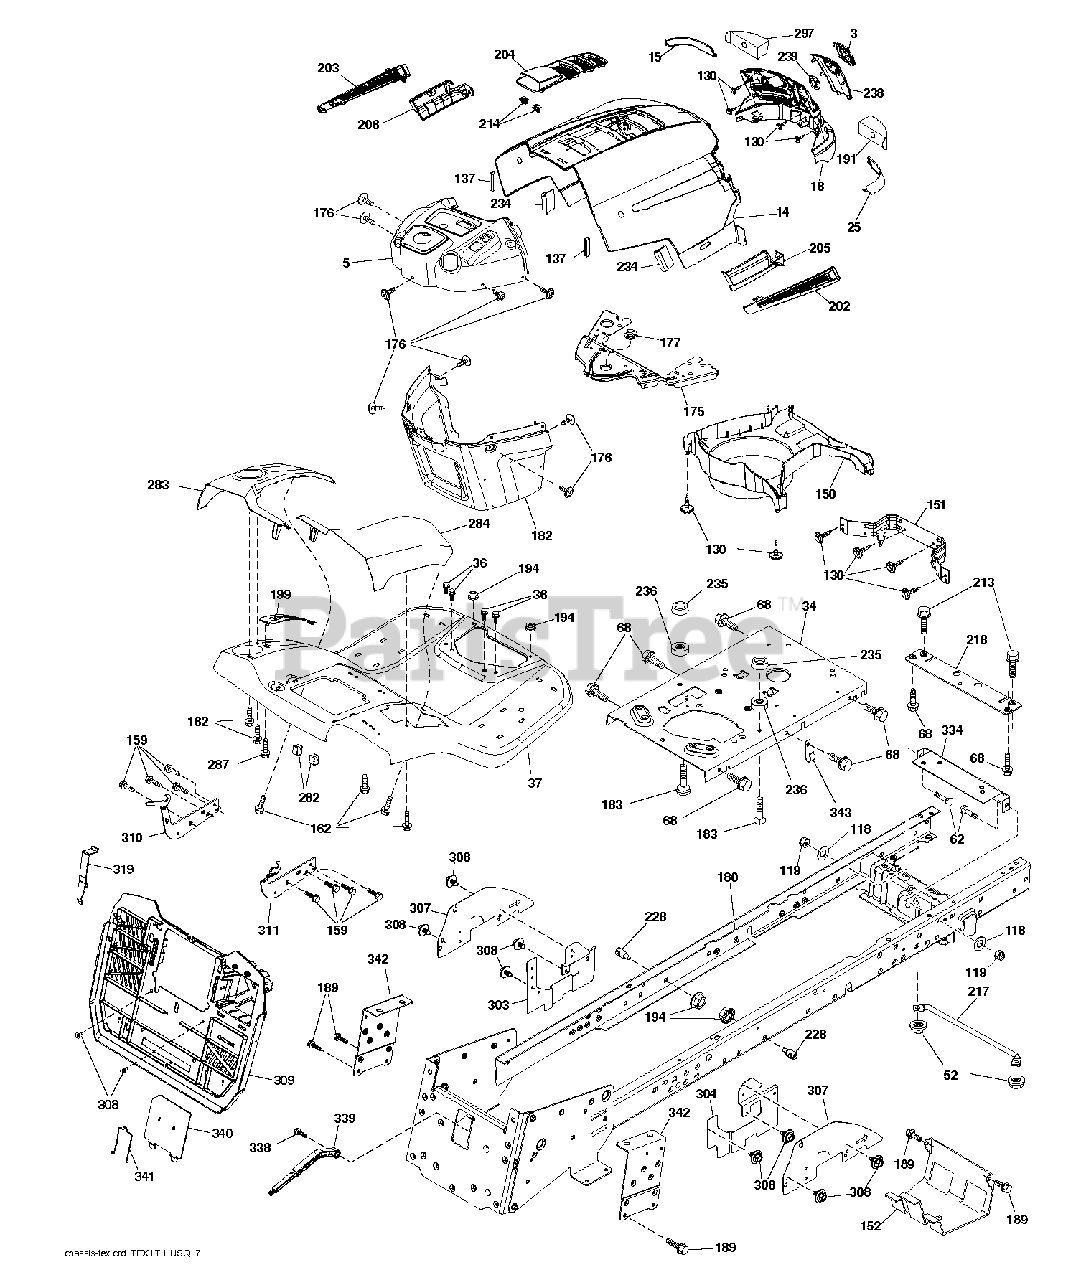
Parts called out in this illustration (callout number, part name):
3	LOGO.HUSQ.GT.LT.CROWN.H
5	DASH.HUSLT.PTO.RS.CHG.SRV.498
14	HOOD.HUSQVARNA.LT.ORANGE
15	LENS.HUSQVARNA LT.RH
18	GRILLE.SVC.HUSQVARNA.GREY
25	LENS.HUSQVARNA LT.RH
34	PLATE.ENGINE.10GA.CRD.GENII
36	SCREW 5/16"
37	FENDER.TEX.SRD.CRD.FRN.GUARDS
52	LOCKNUT
62	BOLT D
68	SCREW LT
118	WASHER
130	SCREW.#10 X 0.750.BOS
137	BUMPER DASH
151	BRACKET PIVOT
152	SHIELD.BROWNING.W/TEX
159	SCREW, 3/8-16X3/4
162	SCREW.HI-LO.CONSOLE
175	CROSSMEMBER
176	SCREW.#10-24X5/8.RN.QU
177	BUSHING STEERING
180	CHASSIS WLDT TEX CRD
182	DASH.LOWER.PREDATOR LT
183	BOLT.5/16-18X1-1/4 FULL THD
189	SCREW
191	INSERT.REFLECTIVE.RH.
194	NUT LOCK HEX FLANGE 5/16-18
199	PLATE DECK LIFT
202	VENT.SIDE.HUSQVARNA.LT.RT
203	VENT.SIDE.HUSQVARNA.LT.LFT
204	SUBASM.TOP.VENT.HUSQ.LT
205	SKIRT.SIDE.HUSQVARNA.LT.RT
206	SKIRT.SIDE.HUSQVARNA.LT.LEFT
213	BOLT
214	CLIP.RETAINER.TINNER.
217	ROD.PIVOT.HOOD
218	X-PIECE.HOOD.STOP.NON/
228	STUD.FASTNER.W/ANTI-ROTATE
234	BUMPER.HOOD.TEX.HUSQVARNA
235	SPACER FENDER
236	NUT.CENTERLOCK.5/16-
238	TRIM.HUSQ LT.668
282	CLIP.RETAINER.CONSOLE.LT.HUSQ
283	CONSL.DECKLIFT.LH.SRD.TEX.CRD
284	CONSL.SHFT.PEDAL.RH.SRD.TEXCRD
287	SCREW 1/4X20
297	INSERT REFLECTIVE
303	SHIELD.LWR.LH.LT.30"CRDSRD.PNT
304	SHIELD.LOWER.RH.CRD.GEN.PNT
307	SHIELD.UPPER.CRD.SRD.ISO
308	BOLT, 5/16-18 X 1 3/4
309	BACKPLATE.TEX.CRD
310	BRACKET BRACKET.LH FRONT BAG H
311	BRACKET BRACKET.RH FRONT BAG H
319	BRACKET.ACTUATOR.BAGGER.SRD
334	BRACKET.ENGINE
338	BOLT BOLT SHOULDER
339	LEVER LEVER BAGGER
340	DOOR.PNT.BATTERY.TRY.TEX.CRD.
341	LATCH
342	SUPPORT SUPPORT FENDER
343	CLIP CLIP
